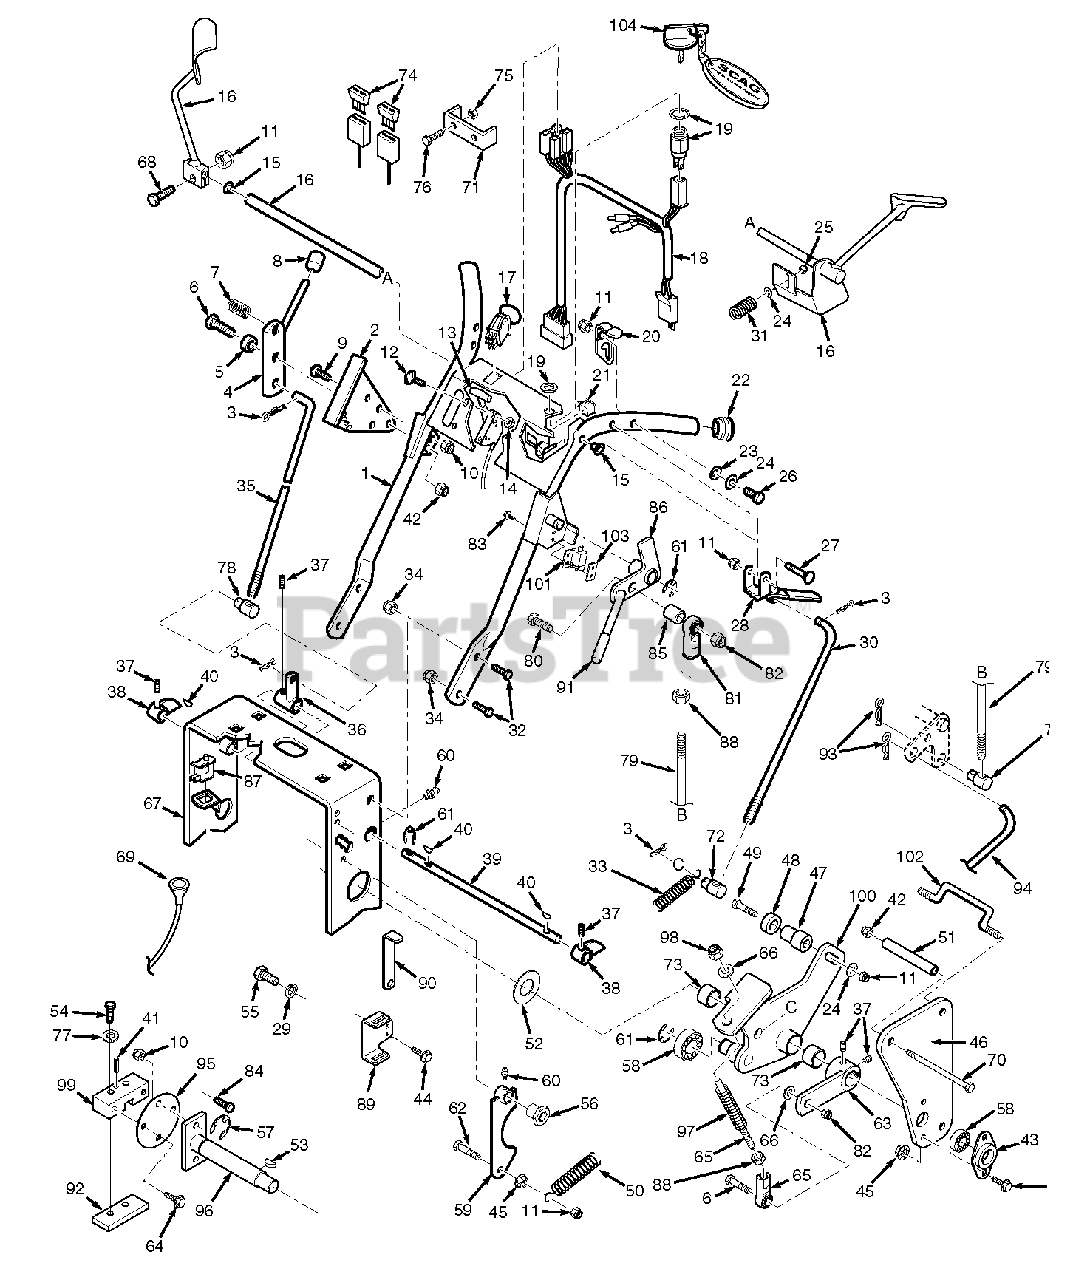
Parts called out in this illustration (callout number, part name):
1	Upper Handle Wlmt. W/Decals
2	Quadrant, Speed Control
3	Hairpin, .094 x 1.19
4	Lever, Speed Adjustment
5	Bushing, Speed Adjustment Lever
6	Hex Head Bolt, 3/8-16 x 1.5'
7	Ball Plunger
8	Knob, Speed Adjustment
9	Capscrew, 1/4-20 x 3/4' FHHS
10	Nut, 1/4-20 Elastic Stop
11	Nut, 5/16-18 Elastic Stop
12	Screw, #10-32 x 1/2' PW HD
13	Throttle Control
14	Nut, #10-32 Serr. Flange
15	Bushing
16	Handle, Oper. Presence-RH
16	Handle, Oper. Presence-LH
17	Switch, Electric Clutch Engage
18	Wire Harness, Manual Start
18	Wire Harness, Electric Start
19	Key Switch, Manual Srt. (inc. Hdw)
19	Key Switch, Electric Srt. (inc. Hdw)
20	Neutral Latch-RH
20	Neutral Latch-LH
21	Switch, Neutral Interlock
22	Plug, Handlebar
23	Washer, Curved Spring
24	Flat Washer
25	Nut, 5/16-18 Elastic Stop
26	Hex Head Bolt, 5/16-18 x 2'
27	Hex Hd. Bolt, 5/16-18 x 2.5'
28	Lever, Steering Control
29	Lockwasher, 3/8 Spring
30	Rod, Steering Control
31	Spring, Operator Presence
32	Capscr., 3/8-16 x 1' Ser. Flange
33	Spring
34	Nut, 3/8-16 Serr. Flange
35	Rod Speed Control
36	Bellcrank, Speed Control
37	Setscrew, 1/4-28 x .25'
38	Cam, Speed Control (incl. 37)
39	Jackshaft, Speed Control
40	Key, 1/8 x 1/2' Woodruff
41	Roll Pin, 3/16-.75
42	Nut, Elastic Stop 3/8-16
43	Flange, Bearing
44	Capscrew, 5/16-18 x 1' Serr. Flg.
45	Nut, 5/16-18 Serrated Flange
46	Plate, Side
47	Spacer, Neutral Bearing
48	Bearing, Speed Ctrl. Bellcrank
49	Hex Head Bolt, 5/16-18 x 1-3/4'
50	Spring, Return
51	Spacer, Side Plate
52	Flatwasher, .766 x 1.25 x .035
53	Key, Woodruff, 3/16 x .75
54	Bolt, Hex Head, 1/4-20 x 1.25'
55	Bolt, Hex Head, 3/8-16 x 1'
56	Bushing, Brake
57	Clip, Retaining .750 diameter
58	Bearing, Ball Neutral Return
59	Cam, Neutral (incl. grease ftng.)
60	Grease Fitting, 1/4-28 UNF
61	Retaining Ring, 5/8'
62	Hex Head Bolt, 5/16-18 x 1'
63	Lever, Speed Control
64	Bolt, Hex Head 1/4-20 x.75'
65	Linkage Assembly
66	Flat Wshr., 15/16 x .3906 x 12 ga
67	Deck, Engine 20' Wide
68	Hex Head Bolt, 5/16-18 x 1.25'
69	Choke Control
70	Bolt, Hex Head 3/8-16 x 4.25'
71	Fuse Holder - 21KAE
72	Swivel Joint, Steering Rod
73	Bushing
74	Blade Fuse, 20A - 22FSE
75	Nut, #10-32 Elastic Stop - 2FSE
76	Screw, #10-32 x 1.5' Phillips - 22FSE
77	Lockwasher, 1/4'
78	Swivel Joint
79	Rod, Brake Lever
80	Hex Hd. Bolt, 3/8-16 x 2'
81	Ball Joint, RH Thread
82	Nut, 3/8-16 Elastic Stop
83	Screw #10-32 Sltd Hex Wshr Hd
84	Bolt, 1/4-20 x .75'
85	Spacer
86	Parking Brake Lever with Grip
87	Switch, Safety
88	Nut, 3/8-24
89	Mounting Bracket, Wrench
90	Wrench
91	Grip, Parking Brake
92	Plate, Threaded
93	Hairpin, .094 x 1.62'
94	Rod, Lower Brake
95	Plate, Coupler
96	Shaft, Pump Control
97	Spring
98	Nut, 3/8-16 Elastic Stop
99	Block, Pump Control
100	Control, LH (inc. bush. & decal)
100	Control, RH (inc. bush. & decal)
101	Switch, Parking Brake
102	Rod, Offset
103	Plate, Threaded
104	Key Chain with Keys
104	Key with Shroud
